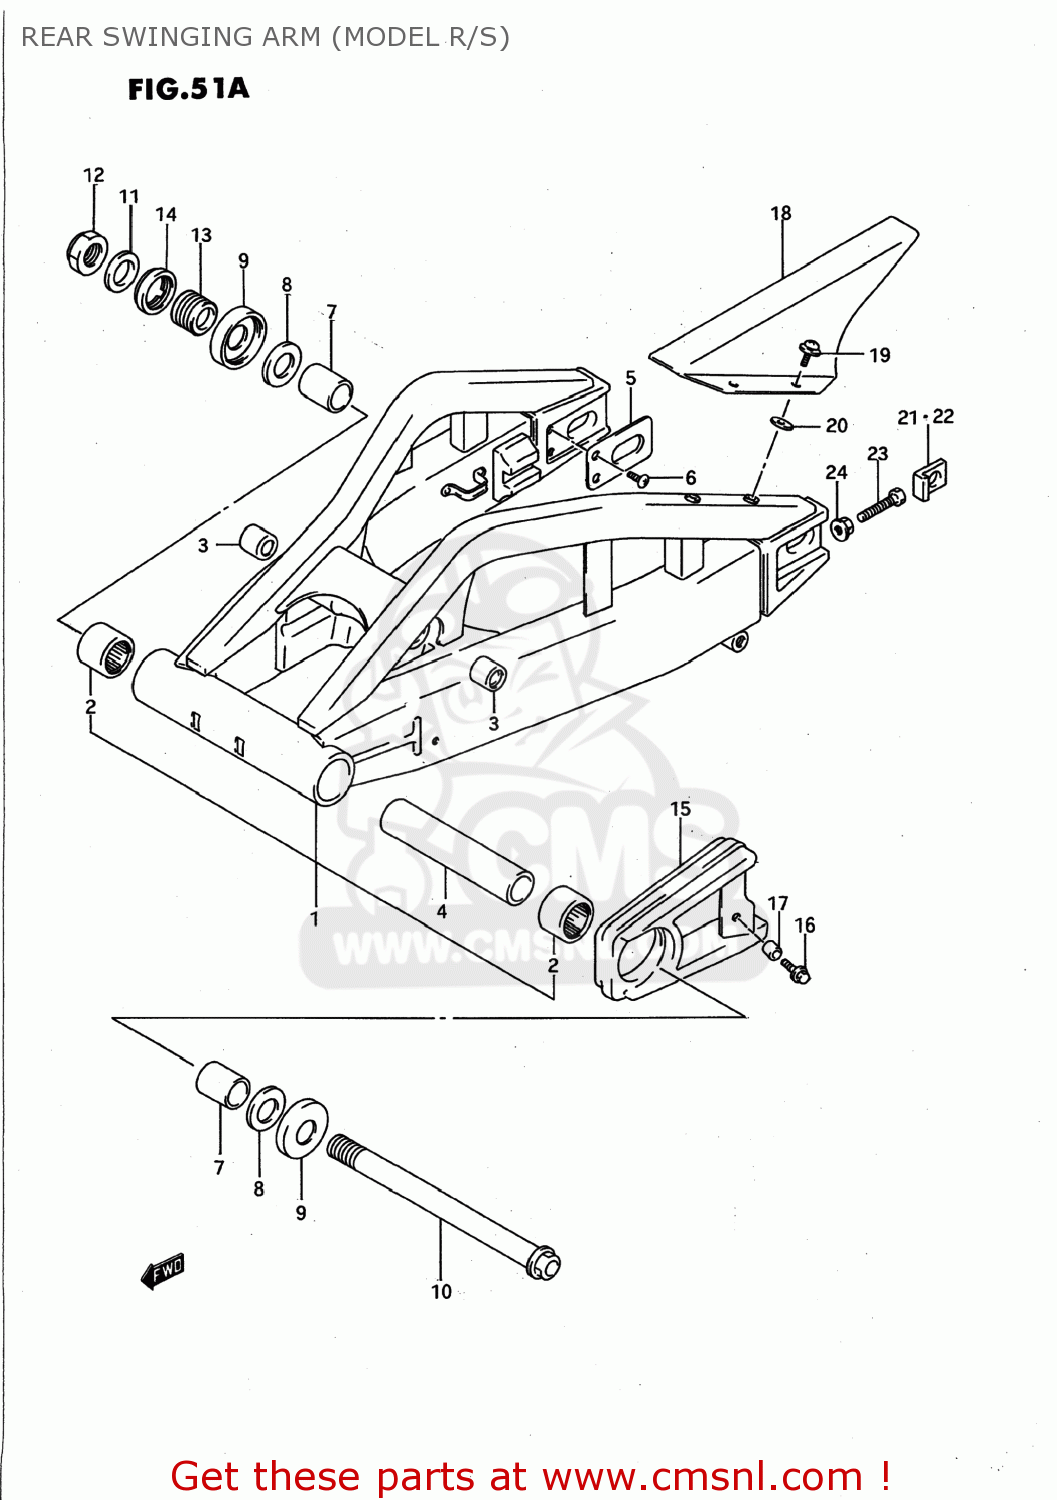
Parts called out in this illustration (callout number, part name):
1	SWING ARM ASSEMBLY,REAR
2	BEARING(30X40X25)
3	BEARING(17X24X20)
4	SPACER (25.4X31.8X157.9)
5	PLATE,RR SWING ARM BRKT
6	SCREW 6X10
7	SPACER,REAR SWING ARM PIVOT
8	WASHER
9	DUST SEAL,RR SWGARM PIVOT
10	SHAFT,REAR SWING ARM PIVOT
11	WASHER(25.2X42X3.2)
12	NUT
13	BOLT,REAR SWING ARM PIVOT
14	NUT,REAR SWING ARM PIVOT BOLT
15	BUFFER,CHAIN TOUCH DEFENSE
16	BOLT 6X20,WITH PLAIN WASHER
17	SPACER
18	CASE,CHAIN
19	SCREW(6X20)
20	WASHER
21	WASHER,CHAIN ADJUSTER
22	WASHER,CHAIN ADJUSTER
23	BOLT(8X50)
24	NUT
